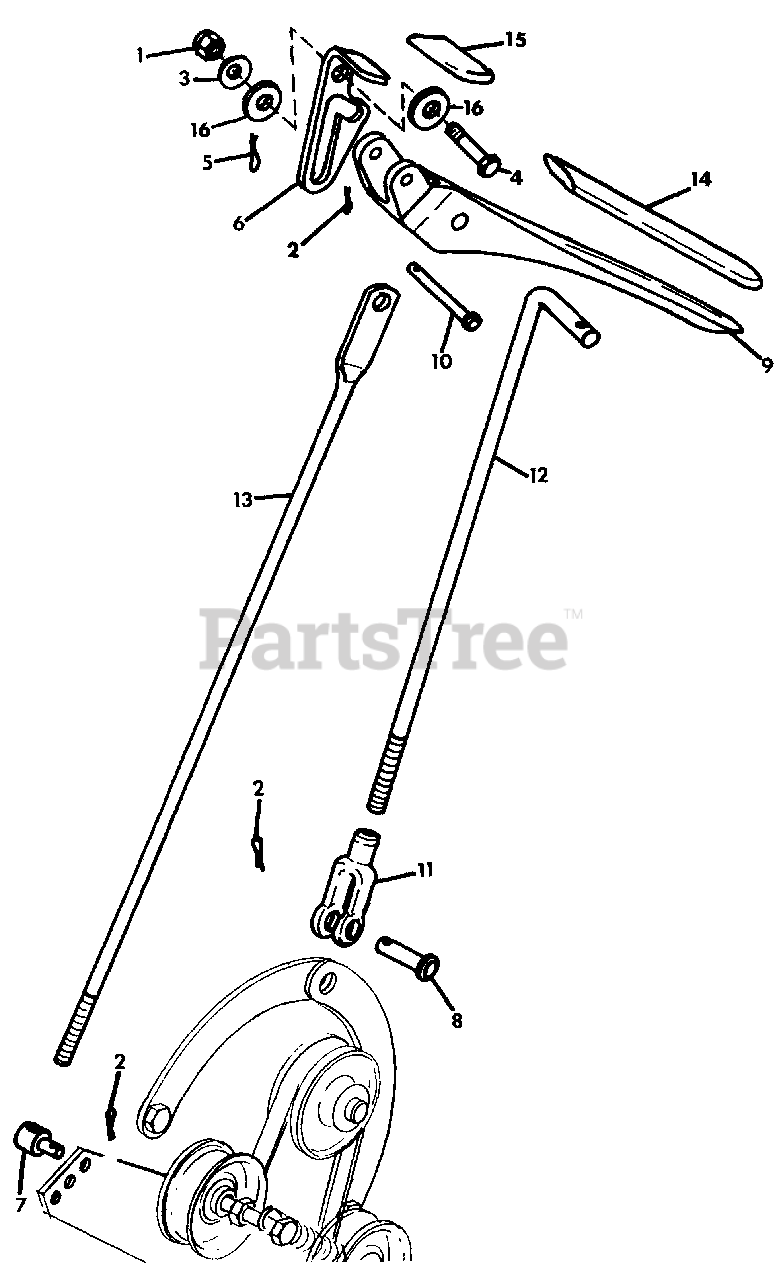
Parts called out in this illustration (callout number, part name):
1	NUT, LOCK 1/4-20
2	PIN, COTTER .09X.625
3	WASHER, SPRING
4	BOLT, HEX 1/4-20X1.75
5	PIN, COTTER .06X.50
6	LEVER, CLUTCH-BRAKE LOCK R.H.
7	PIVOT, BRAKE ROD
8	PIN, CLEVIS .312X.812
9	LEVER, HAND CLUTCH
10	PIN, CLEVIS .187X1.70
11	CLEVIS, 5/16
12	ROD, WHEEL CLUTCH ACTUATING
13	ROD, BRAKE
14	GRIP, HANDLE
15	TIP, VINYL
16	WASHER, FRICTION
